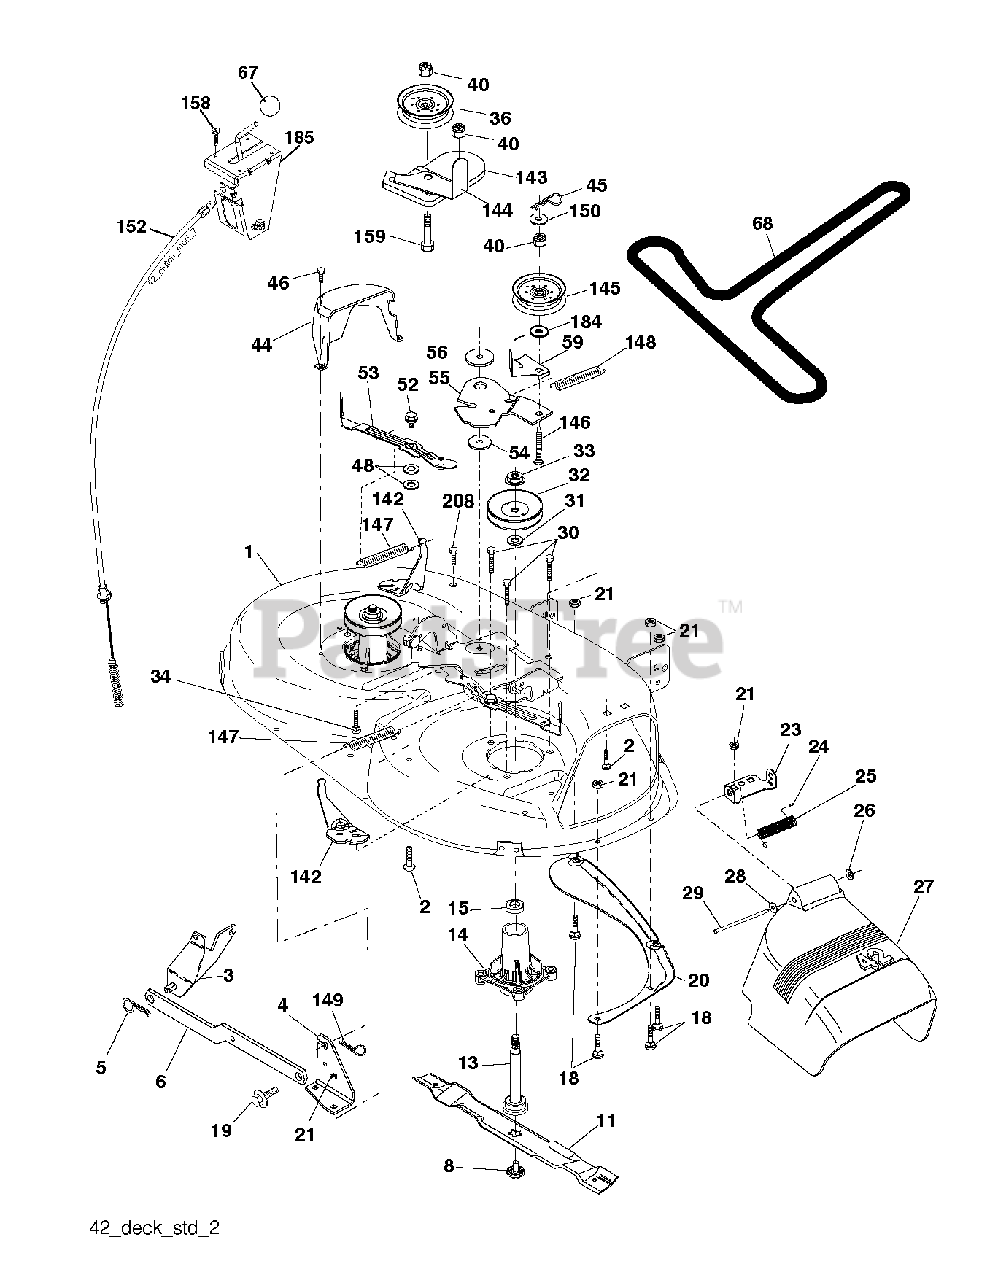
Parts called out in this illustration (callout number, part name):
2	BOLT
3	BRKT ASM SWAY BAR
4	BRACKET SWAY BAR 42" DECK
5	RETAINER-SPRNG RB
6	BAR SWAY DECK
8	BOLT.WASHER.ASM.7/16-2
11	42" HI-LIFT BLADE
11	BLADE.42".MULCH
11	BLADE.42"MULCH.PREMIUM
11	BLADE.42SP"3N1.
11	BLADE.42SP"3N1
13	SHAFT.ASM.MDRL.N/GREASE.38
14	HOUSING.MANDREL.4PT.
18	BOLT
19	BOLT SHD 5/16-18
20	BAFFLE.VORTEX
21	LOCKNUT
23	BRKT, DEFL. MOWER
24	CAP-SLEEVE LT
25	SPRING TORSION
26	NUT PUSH M
27	SHIELD DEFLECTOR
28	WASHER
29	ROD.HINGE
30	SCREW, WASHER HEAD
31	WASHER.SPACER.MANDREL
32	PULLEY/MANDREL
33	NUT.FLANGE.LOCK.TOP
34	BOLT.3/8-16X1.50
36	FLAT IDLER PULLEY
40	NUT LOCK FLG 3/8-16 UNC
44	GUARD MANDREL LH BLACK
45	RETAINER M
46	SCREW.1/4-20X5/8
52	BOLT.SHOULDER.5/16-18
53	ARM BRAKE ASSY
55	ARM IDLER 42" MOWER LT/YT
56	SPACER.RETAINER.MOWER
59	GUARD, BELT
67	KNOB T (3/8 HOLE)
68	BELT V SECONDARY
142	ANCHOR SPRING BRAKE MOWER
143	BRACKET, ARM IDLER
144	KEEPER.BELT.42".CLUTCH.CABLE
145	PULLEY
146	BOLT, CARRIAGE IDLER BLACK
147	SPRING EXTENSION
148	IDLER RETURN SPRING
149	SPRING.RETAINER.YELLOW.ZINC
150	WASHER LT
152	CLUTCH.CABLE.ASM/42"MOWER
158	SCREW
159	BOLT
184	WASHER
185	HEAD ASM. CABLE CLUTCH
208	SCREW 3/8-16X1/2
